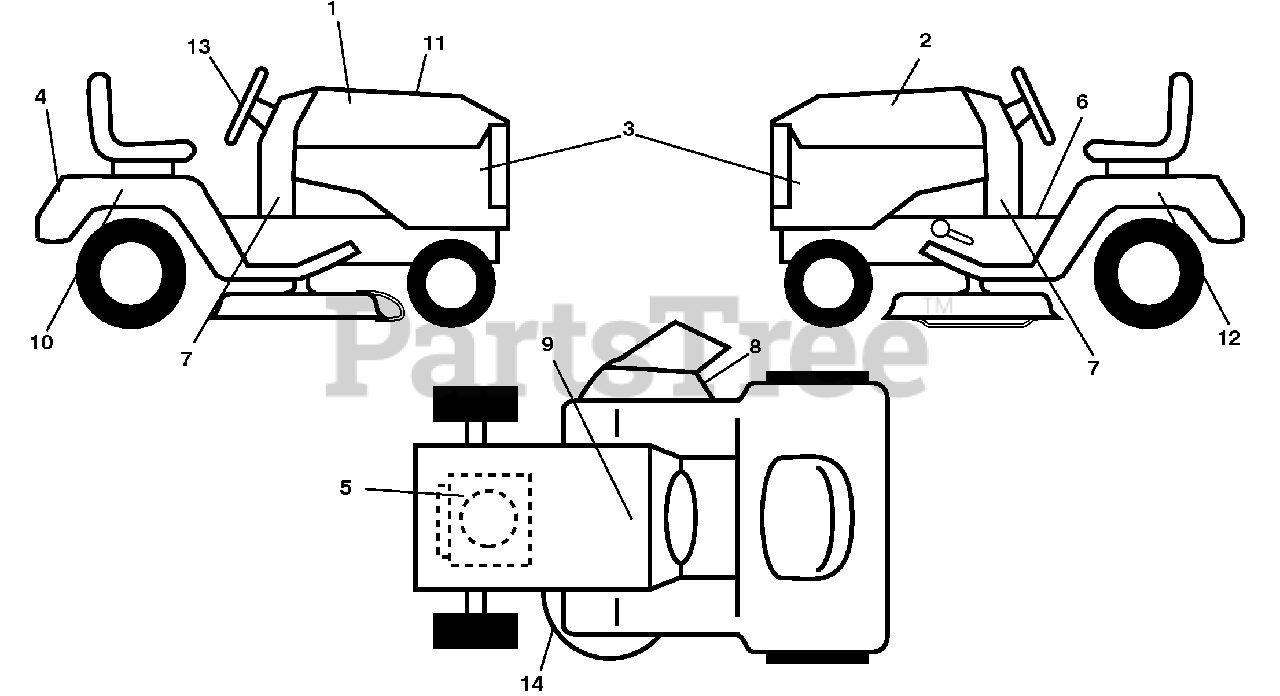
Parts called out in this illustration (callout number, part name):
1	Decal, Hood RH
2	Decal, Hood LH
3	Decal, Side Panel
4	Decal, Fender
5	Decal, Eng H.P.
6	Decal, Fender Operator's
7	Decal, Lower Dash
8	Decal, Warning
9	Decal, Battery Dnge/Poi
10	Decal, Fender SD RH
11	Decal, Replacement
12	Decal, Fender SD LH
13	Decal, Steering Wheel
14	Decal, Mower Schematic
14	Pad, Footrest Control
14	Decal, Bypass
14	Pad, Footrest, LH
14	Manual, Operator's (Eng/French)
14	Manual, Parts (Eng/French)
